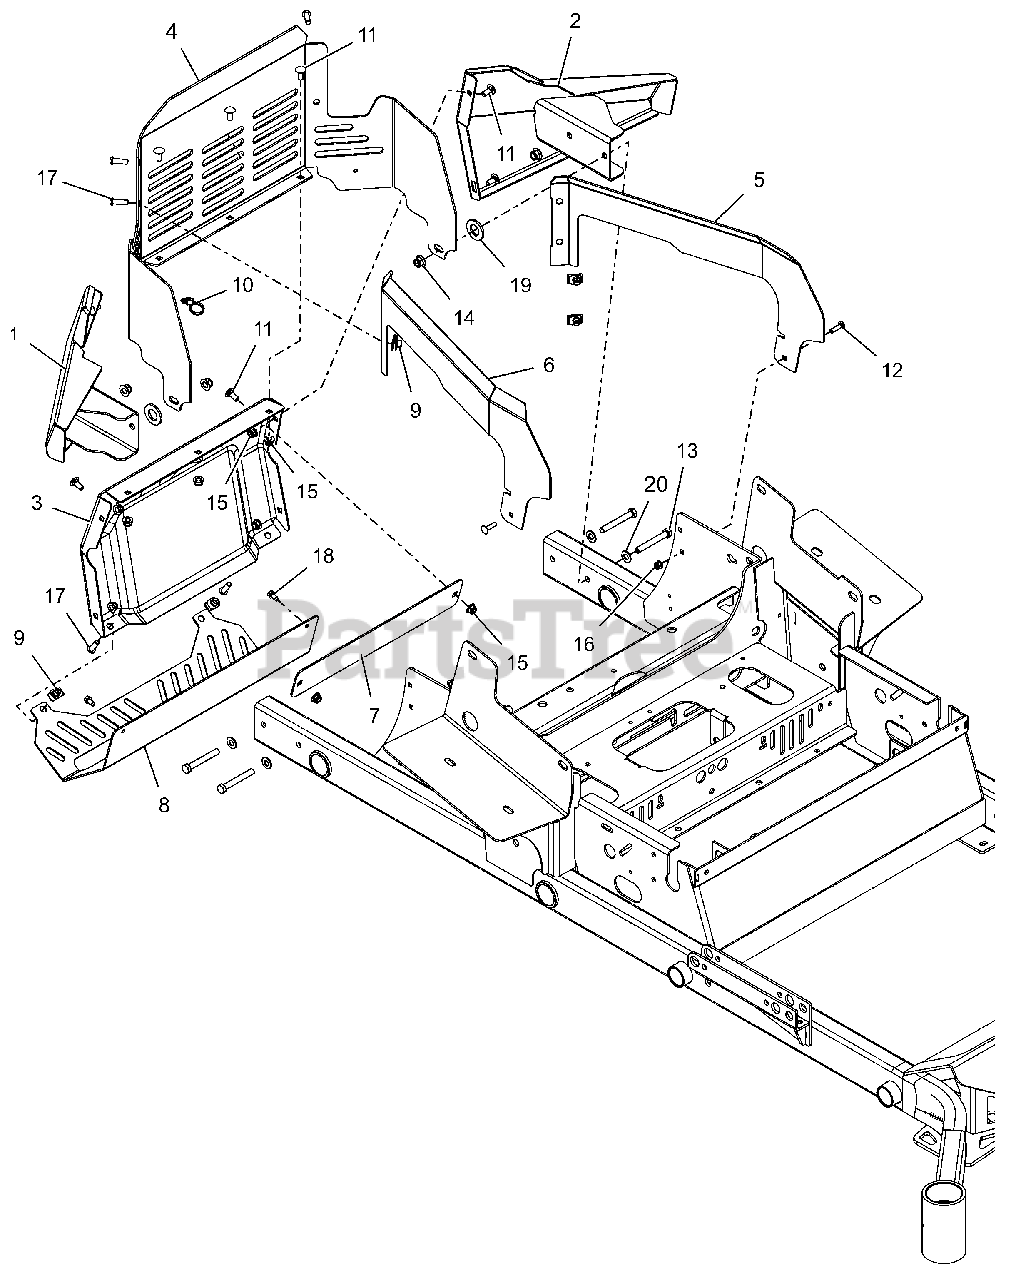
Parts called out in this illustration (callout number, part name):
1	WMT,RH REAR BMPR WING W/DECAL
2	WMT,LH REAR BMPR WING W/DECAL
3	PT200/400 REAR BUMPER - BLACK
4	PT400 ENGINE GUARD - BLACK
5	HOOD STYLE TRIM (LEFT) - RED
6	HOOD STYLE TRIM (RIGHT) - RED
7	BACKER PLATE - RED
8	PT200/400 MUFFLER GUARD - BLK
9	NUT-CLIP RETAINER 5/16-18X.56
10	CABLE TIE W/ TREE (.25 HOLE)
11	@BLT-RDHDSQNK .31-18X.75 G5YZ
12	@BLT-RDHDSQNK .25-20X1.00 G5YZ
13	@BLT-HEX .38-16X2.75 GR5 YWZC
14	@NUT-LK-NYL-FLG .38-16 YWZC
15	@NUT-LK-NYL-FLG .31-18 YWZC
16	@NUT-LK-NYL-FLG .25-20 YWZC
17	SCR-SKH .31-18X1.0 BTNHD YWZC
18	SCR-TAP .25-20X.50 HWH TR YWZ
19	@WSHR-FL-STL.812X1.50X.135YWZC
20	@WSHR-FL-STL.406X.812X.065 YWZ
